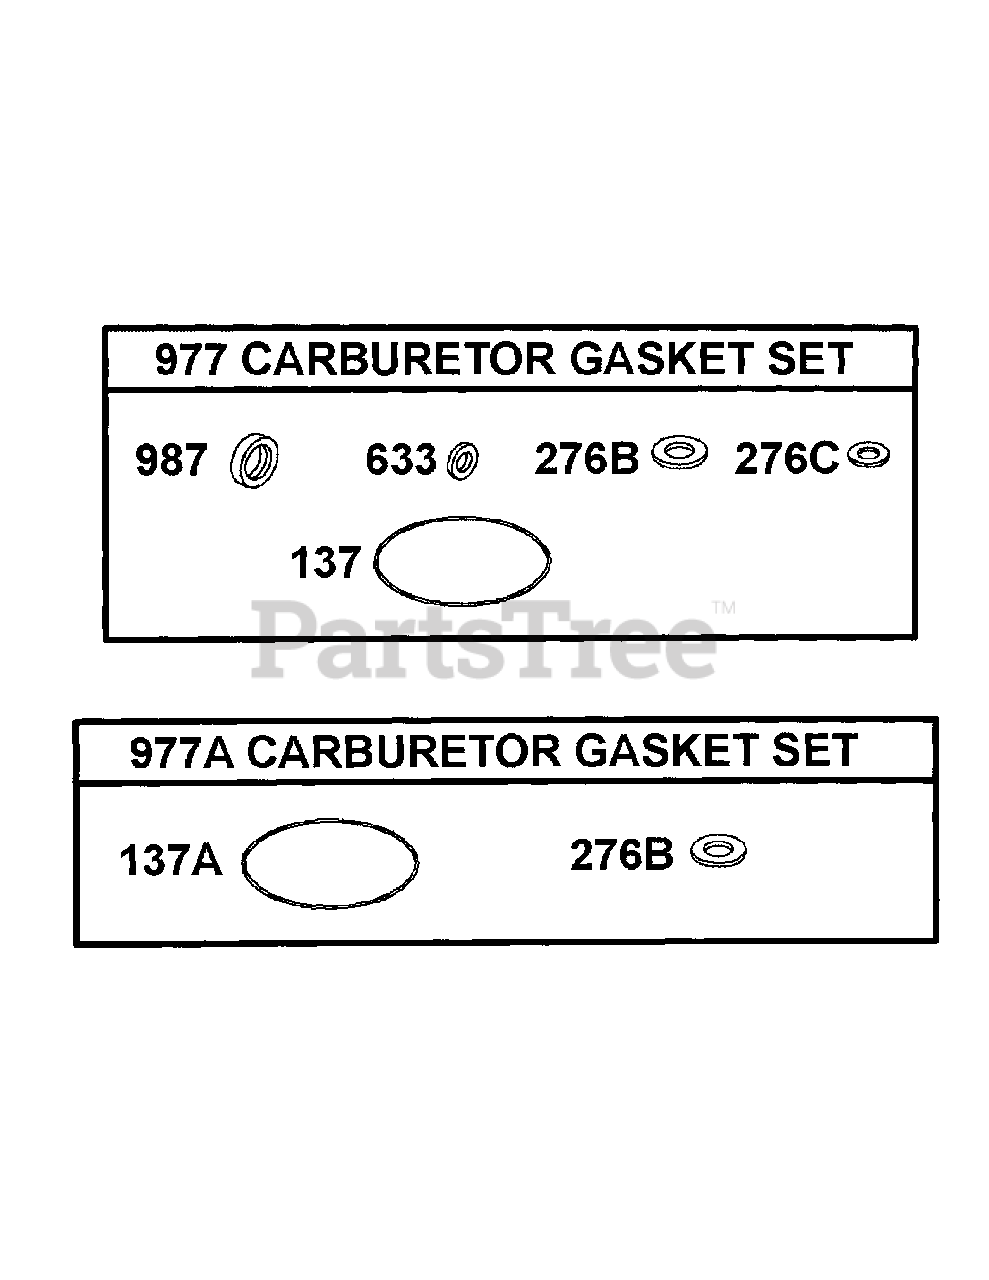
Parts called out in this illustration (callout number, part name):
137	Gasket-Float Bowl
276B	Washer-Sealing (Float Bowl)
276C	Washer-Sealing (Carburetor Plug)
633	Seal-Choke/throttle Shaft
977	Gasket Set-Carburetor
977A	Gasket Set-Carburetor
987	Seal-Throttle Shaft
